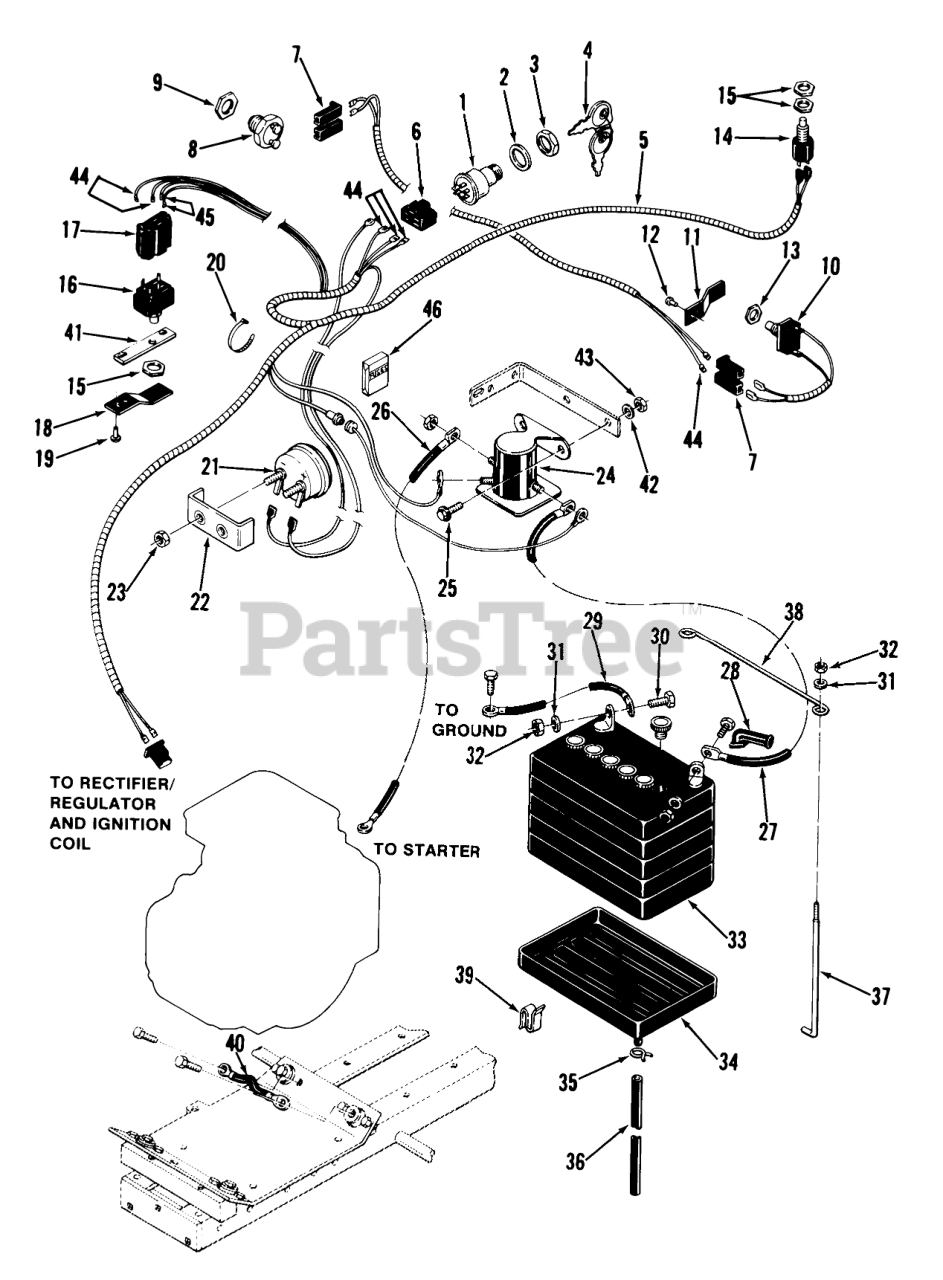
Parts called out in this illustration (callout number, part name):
1	SWITCH-IGNITION
2	LOCKWASHER
4	Key-EL
5	WIRING HARNESS
6	CONNECTOR-5 WAY-SERV
7	CONNECTOR BODY
8	SWITCH-INTERLOK CLUT
9	NUT-SPECIAL 9/16-18
10	Interlock Switch-Transmission
11	CLIP-SWITCH
12	RIVET
13	NUT-HEX
14	SWITCH
15	NUT-HEX
16	SWITCH-CLUTCH
17	CONNECTOR 5 WAY
18	CLIP-SWITCH
19	RIVET
20	PLASTIC TIE
21	AMMETER W/CLAMP
22	Clamp
23	HEX NUT 10-32 E.S.
24	SOLENOID
25	Screw
26	Cable-Solenoid To Starter
27	Cable
28	Terminal Cover
29	Wire
30	Bolt
32	Nut
33	Battery
34	TRAY-BATTERY
35	Clamp
36	FUEL HOSE 13" OF 6554
37	Hook
38	ROD-HOLD DOWN
39	CLIP
40	WIRE-GROUND
41	CLAMP-PTO SWITCH
42	LOCKWASHER
43	Nut
44	Terminal
45	TERMINAL-TAB RCPT
46	Fuses 3AG 25AMP
